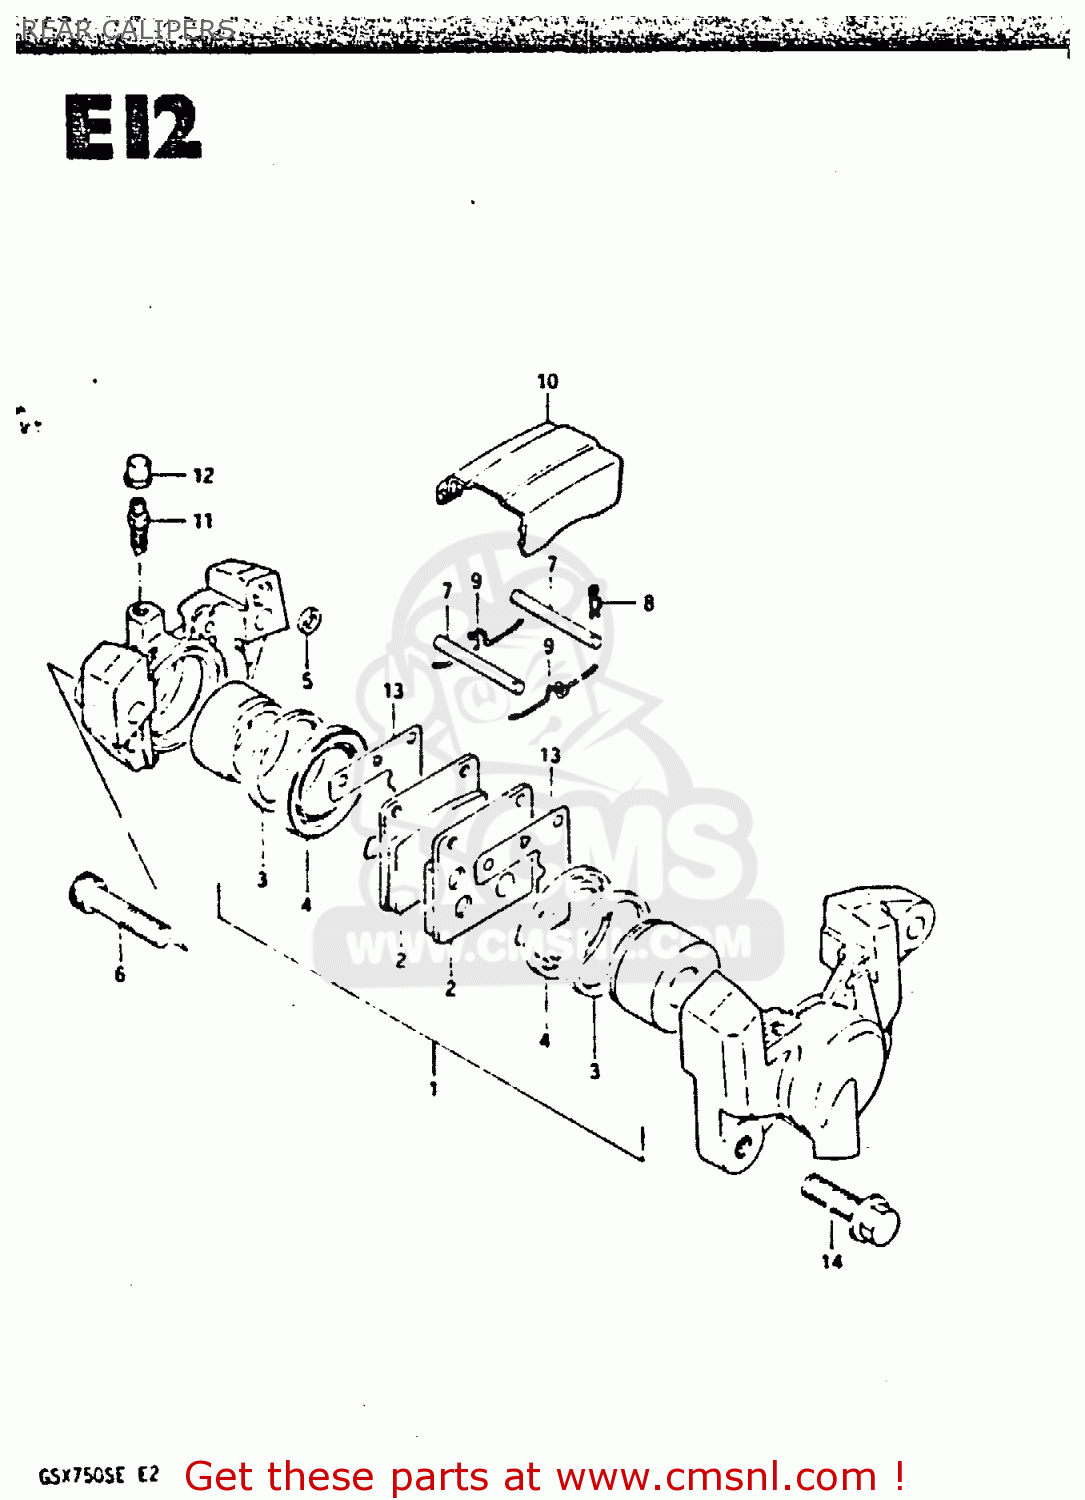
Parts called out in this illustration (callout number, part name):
1	PISTON & PAD SET
2	PAD
3	SEAL,PISTON
4	BOOT,PISTON
5	SEAL,JOINT
6	BOLT,CALIPER HOUSING
7	PIN,PAD
8	CLIP,PAD PIN
9	SPRING
10	COVER,DUST
11	BLEEDER
12	CAP,BREATHER
13	SHIM,RR CALIPER
14	BOLT 10X30
